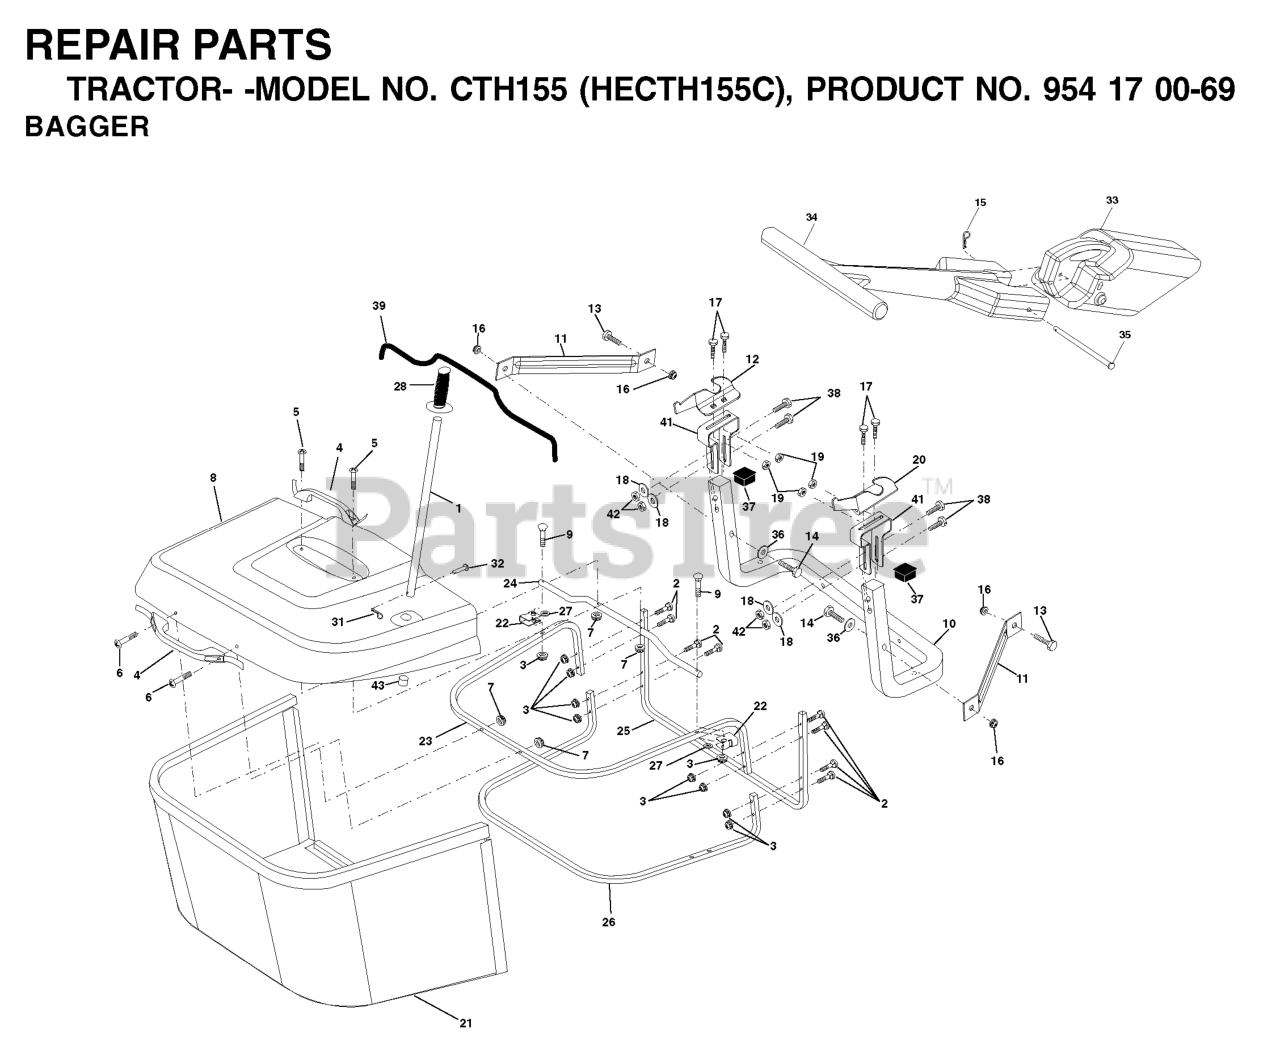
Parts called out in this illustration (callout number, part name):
1	TUBE HANDLE
2	Bolt Carriage 1/4-20 x 2.0 Gr.5
3	NUT T
4	HANDLE.BAGGER.W/LVRS.BLK.CRD
5	SCREW.PAN.HEAD
6	REPL BY 532 75 00-29
8	COVER.PNT.BGR.CRD.WSLOTS.MS668
9	Bolt Carriage 1/4-20 x 2.25d x Gr.5
10	TUBE
11	BRACKET.SUPPORT.UPPER.BAG.CRD
14	BOLT-HEX EAK
15	RETAINER-SPRNG RB
16	NUT LOCK FLG 3/8-16 UNC
17	RP BOLT 5/16-18 X3/4 ZN/YEL GR
18	WASHER M
19	NUT LOCK HEX FLANGE 5/16-18
20	BRACKET
21	GRASS BAG
22	BRKT.SIDE.BAG.CRD
23	TUBE.UPPER.BAG.CRD
24	TUBE.PIVOT.BAG.CRD.BLACK
26	TUBE.LOWER.BAG.CRD
28	GRIP.HANDLE.BLACK
31	RETAINER M
32	RIVET,DRILLED
33	PLUG.MULCHER.92 CRD
34	HANDLE.MULCHER.92.CRD (2 2)
36	WASHER
37	Plug Support Bagger CRD
38	BOLT.5/16-18X2.5
39	SEAL.TRIM.37'
41	BRKT.VERT.ADJ.BAGGER.CRD
42	NUT.71038.31-18.HEX.NYLOCK
43	PLUG, TUBING END
